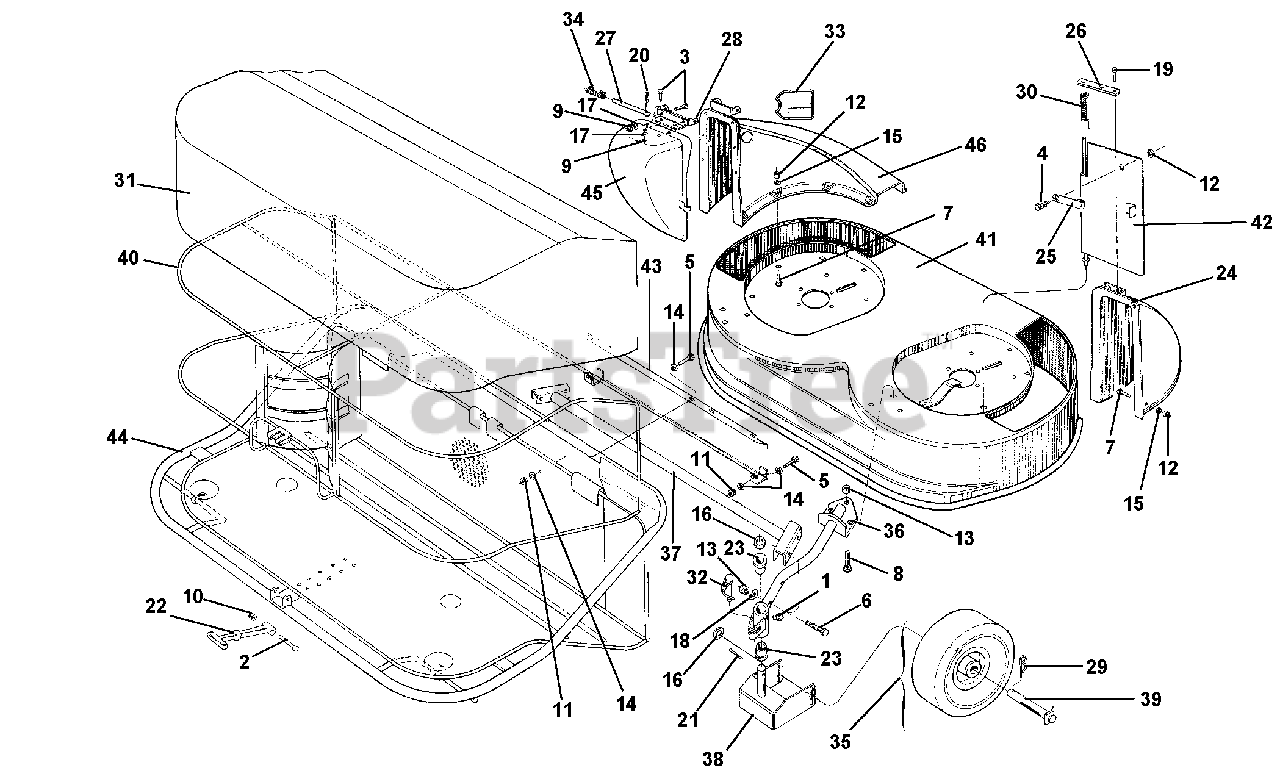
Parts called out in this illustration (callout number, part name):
1	LUBRICATOR M10
2	SCREW TE M4 X 40
3	SCREW M5 X 10
4	SCREW TE M6 X 14
5	SCREW M5 X 16
6	SCREW TE M8 X 45 UNI 5739-8G
7	SCREW M6 X 20
8	SCREW TTQ M8 X 20 UNI 5731
11	NUT, SELF LOCKING M5 STAND.
12	NUT, SELF LOCKING M6
13	NUT, SELF LOCKING M8
14	WASHER, FLAT 5.3
15	WASHER, FLAT 6.4
16	WASHER, FLAT 21 UNI 1736
17	SUPER WASHER
18	WASHER, LOCK 8.4
19	SCREW 6.3 X 19
20	COTTER PIN A 3 X 15 UNI 1336 AC.
21	PIN, COTTER A 4 X 30 UNI 1336
22	HANDLE RUBBER
24	L.H. CONVEYOR
31	GRASS CATCHER BAG
34	DEFLECTOR SPRING
35	WHEEL 3.00 - 4
36	LONG SUPPORT
41	LAWN MOWER CRANKCASE
43	REAR PROTECTION
44	BAG FRAME BOTTOM
